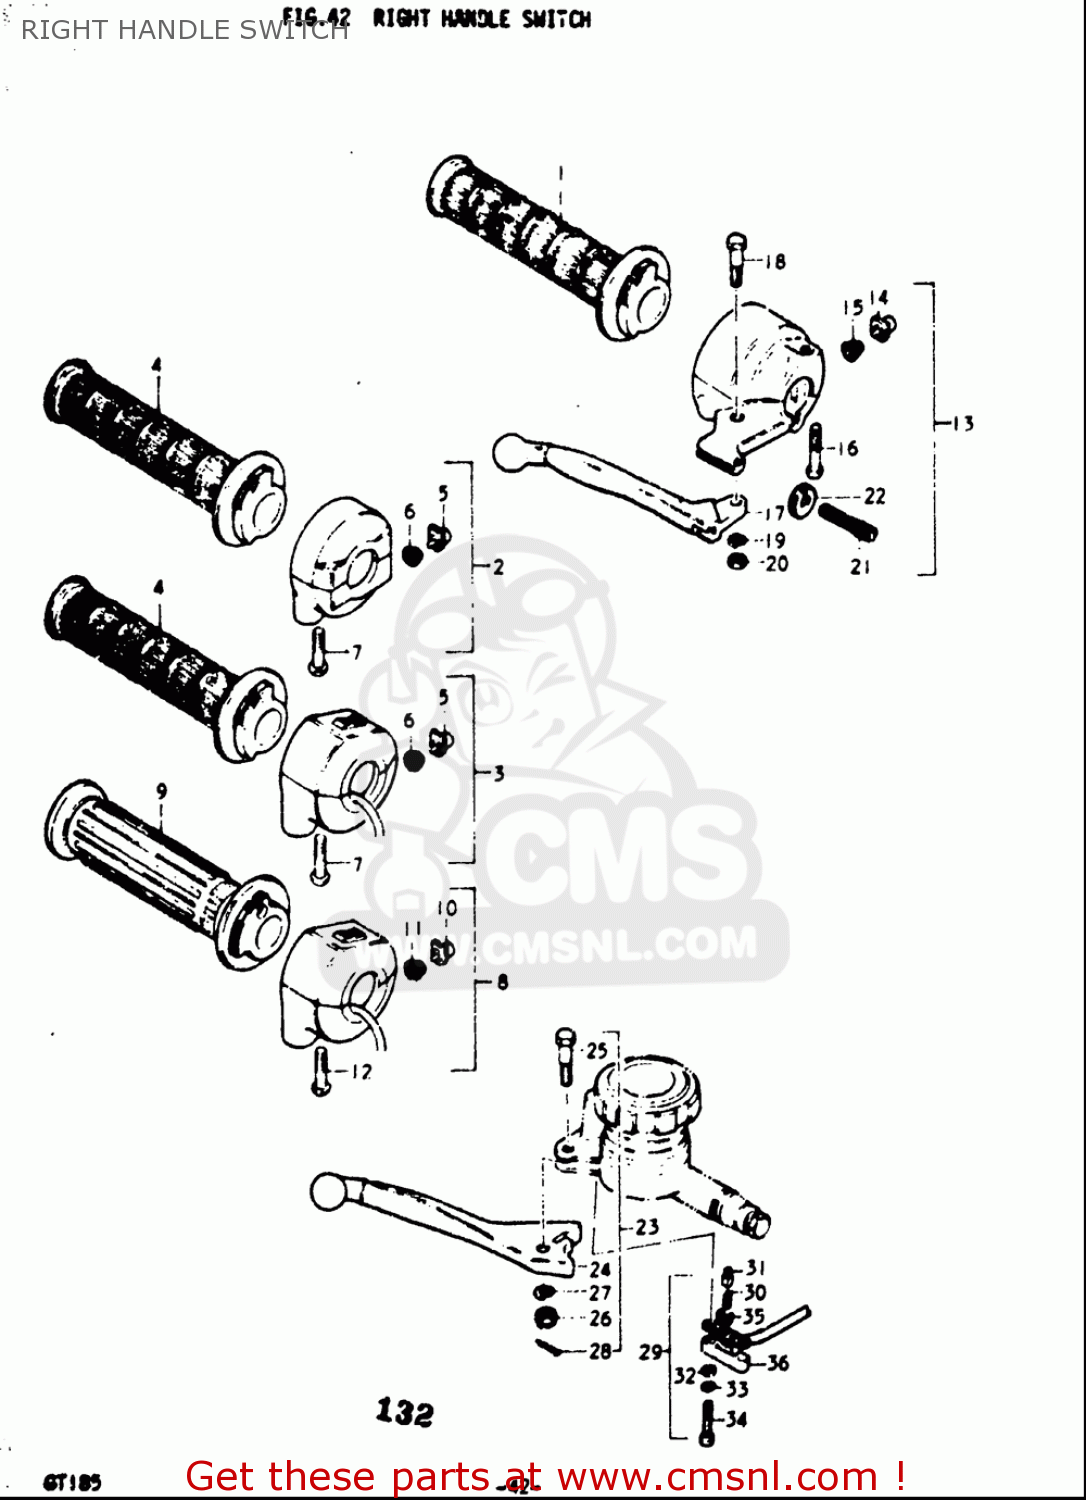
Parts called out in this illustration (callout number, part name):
5	BUTTON
6	SPRING
7	SCREW
9	GRIP,THROTTLE
10	BUTTON
11	SPRING
12	SCREW
14	BUTTON
15	SPRING
16	SCREW
17	LEVER,BRAKE
18	BOLT
19	WASHER,LOCK
20	NUT
21	ADJUSTER,CABLE
22	NUT,CABLE ADJUSTER
24	LEVER,BRAKE
25	BOLT
26	NUT,LEVER FITTNG
27	WASHER,LOCK
28	PIN 16X20
29	SWITCH ASSY,STOP
30	CONTACT,SWITCH
31	CONTACT,SWITCH
32	WASHER
33	WASHER,LOCK
34	SCREW
35	CONTACT,SWITCH
36	COVER,FR BK TERMINAL BASE
